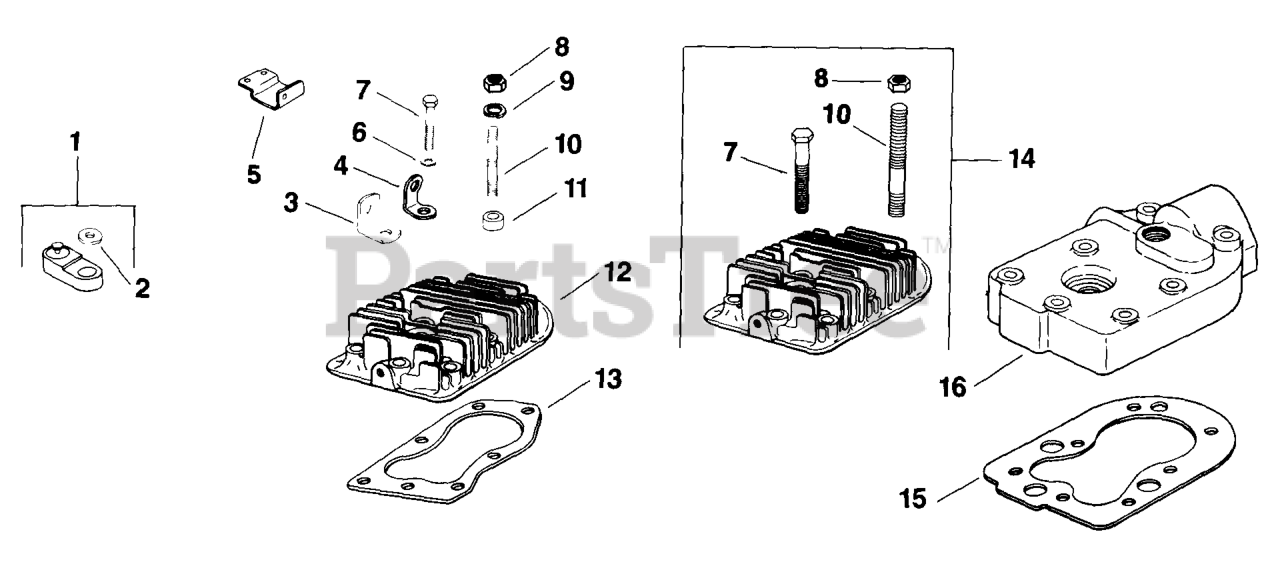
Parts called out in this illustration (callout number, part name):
4	STRAP - USE 28 445 01
6	WASHER, FLAT 5/16"
7	SCREW, SEMS 1/4-20X5/8" USE 25 086 539-S
14	KIT, CYLINDER HEAD - DISCONTINUED
